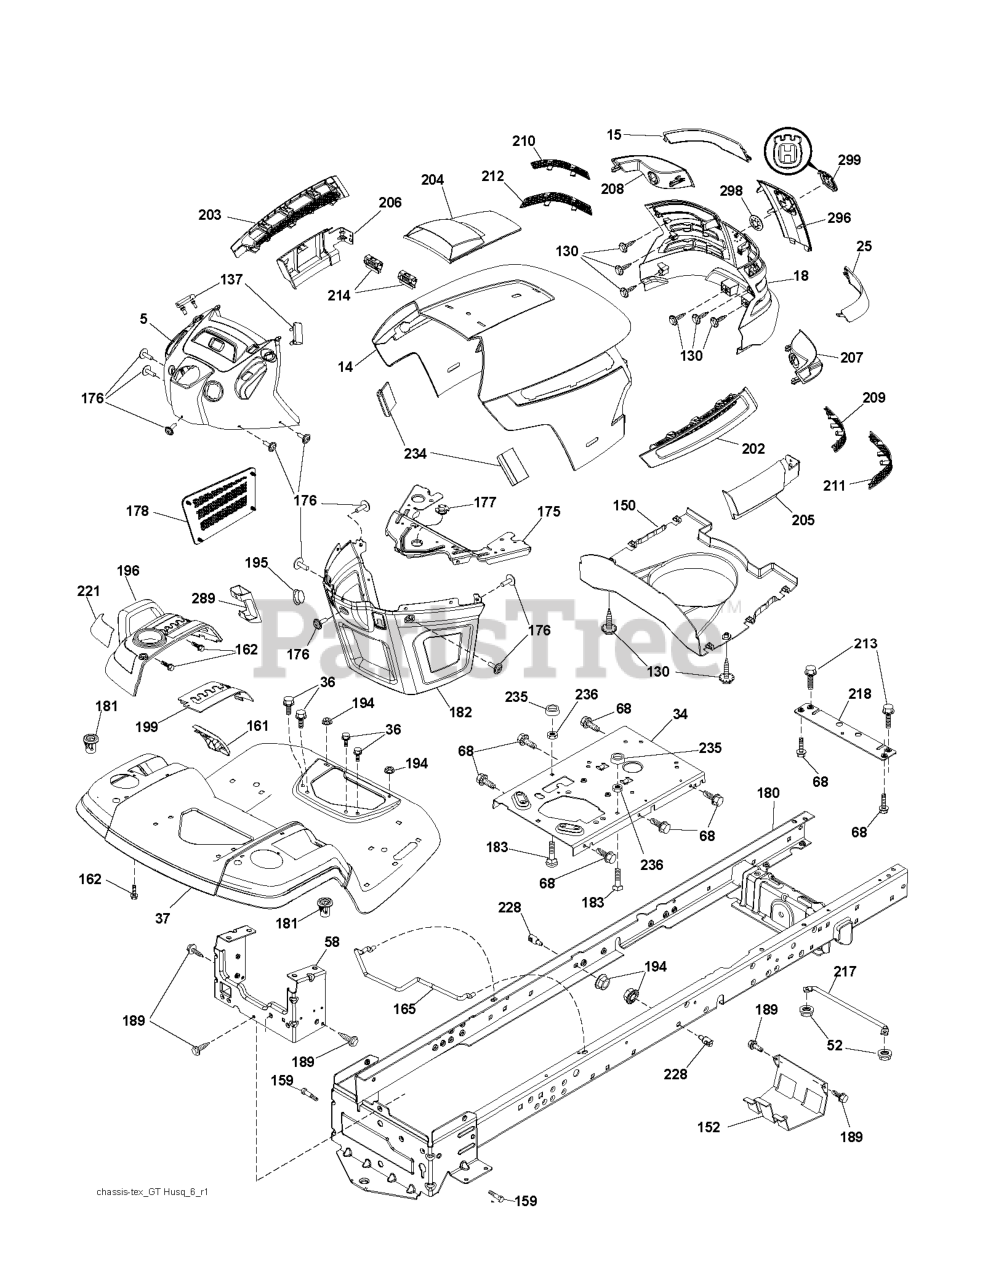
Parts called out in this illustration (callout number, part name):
5	DASH.ASM.HUSQ.GT.E.RECT.W/CK
14	HOOD
15	LENS.LH.TEX.GT.HUSQ.CL
18	GRILL.ASM.HUSQ.TG/CRD.W/TRIM
25	LENS.RH.TEX.GT.HUSQ.CL
34	PLATE.ENGINE.WELDED.CHASSIS
36	SCREW 5/16"
37	FENDER.PNT.TX.GT.CH/FW.ORANGE
52	LOCKNUT
58	DRAWBAR.UPPER.2PC,LRG.FENDER
68	Screw 5/16-18 x 1/2 Hex, Self Tapping 5/16-18 x 1/2
130	SCREW
137	BUMPER DASH
150	AIR.DUCT.TEXGT.HUSQ.31
152	SHIELD.BROWNING.W/TEX
159	SCREW, 3/8-16X3/4
161	CONSOLE.FUEL.WINDOW.HU
162	SCREW.HI-LO.CONSOLE
165	SUPPORT.TANK.REAR.W/TEX
175	PLATE.CROSSMEMBER.HUSQ
176	SCREW.#10-24X5/8.RN.QU
177	BUSHING, STEERING
178	CARGO.ASM.NET.TXGT.W/C
180	CHASS.WLDMNT.TLT.12GA/2PC.20"
181	BUSHING.MNT.FEND.CRGO.
182	DASH.LOWER.COMMON.12V.ADAPTOR
183	BOLT.5/16-18X1-1/4 FULL.THREAD
189	SCREW
194	NUT LOCK HEX FLANGE 5/16-18
195	PLUG.HOLE.DASH.LOWER.12V.BLK
196	RP CONSOLE.ASM.DECKLFT.W/
199	PLATE.DECK.LIFT.HUSQVARNA.GT
202	VENT.SIDE.HOOD.HUSQ.RH.GREY
203	VENT.SIDE.HOOD.HUSQ.LH.GRAY
204	HOOD VENT
205	SKIRT.HOOD.SIDE.HUSQ.RH.GREY
206	SKIRT.HOOD.SIDE.HUSQ.LH.GREY
207	BEZEL.RH.TEX.GT.HUSQ
208	BEZEL.LH.TEX.GT.HUSQ
209	INSERT.HEX.GRILL.HUSQ.GREY
210	INSERT.HEX.GRILL.HUSQ.
211	INSERT.HEX.GRILL.HUSQ.
212	INSERT.HEX.GRILL.HUSQ.
213	BOLT
214	CLIP.RETAINER.TINNER.
217	ROD.PIVOT.HOOD
218	X-PIECE.HOOD.STOP.NON/
221	REFLECTOR.LH.TEX GT HU
228	STUD.FASTNER.W/ANTI-ROTATE
234	BUMPER.HOOD.TEX.HUSQVARNA
235	SPACER FENDER
236	NUT.CENTERLOCK.5/16-
289	PLUG.N/CRUISE.COMMON.YT/GT.BLK
296	TRIM.HUSQ.TG/CRD.SERVICE
298	NUT PUSH M
299	RP LOGO
